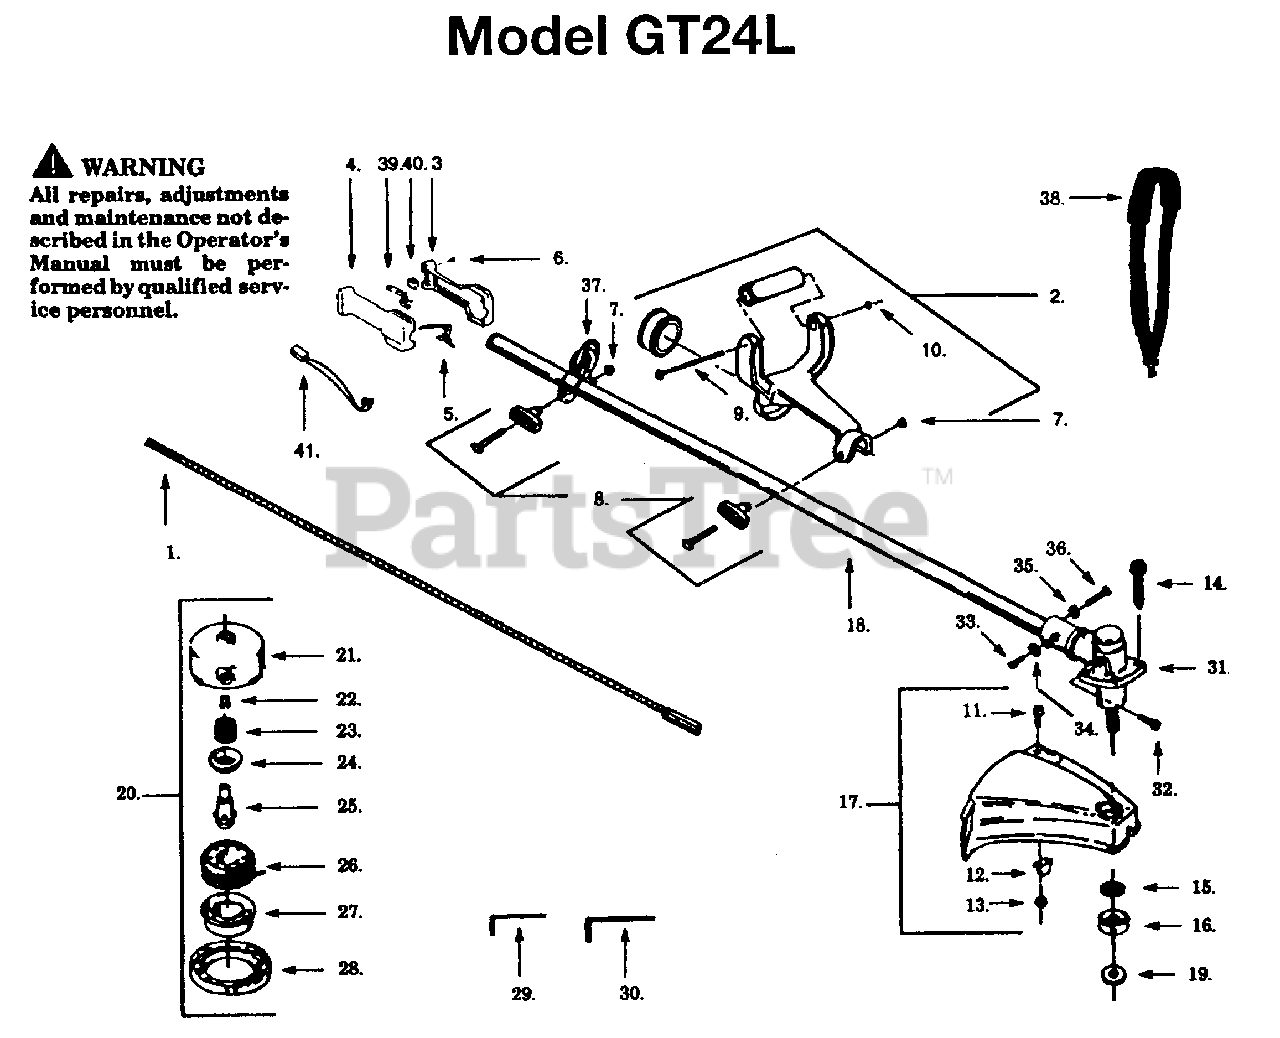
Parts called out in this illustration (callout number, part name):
1	SHAFT-FLEX (57").
2	ASS'Y-HANDLE ANTIVIB
5	THROTTLE TRIGGER
6	SCREW-10-14 X 13/16 (PL
8	KIT "T" HANDLE
9	SCREW-12-24 X 4-11/16 P
10	NUT-12-24 (HEX)
12	LIMITER-LINE
13	NUT 10-24 NYLOC HEX
14	SCREW - SHIELD
17	KIT-SHIELD
18	DRIVE SHAFT HOUSING
19	WASHER-GRASS
20	TAP-N-GO I CCW
21	ASSY-HUB W/LN SAVER
22	SAVER-LINE
24	ADAPTOR SPRING
25	GEAR-DRIVE
27	TAP BUTTON
29	ALLEN KEY
30	ALLEN KEY 3/16''
31	GEAR BOX ASSY/TYPE 1
32	SCREW-5/16-24X3/8 HEX S
33	SCREW-10-24 X 7/16 (HEX
34	LOCKWASHER-LOCATOR-TYPE 2
35	LOCKWASHER
36	SCREW-1/4-20X1 HEX SOC
37	ASSY-CLAMP HARNESS
38	STRAP SHOULDER
40	REPL BY 530 06 95-72
